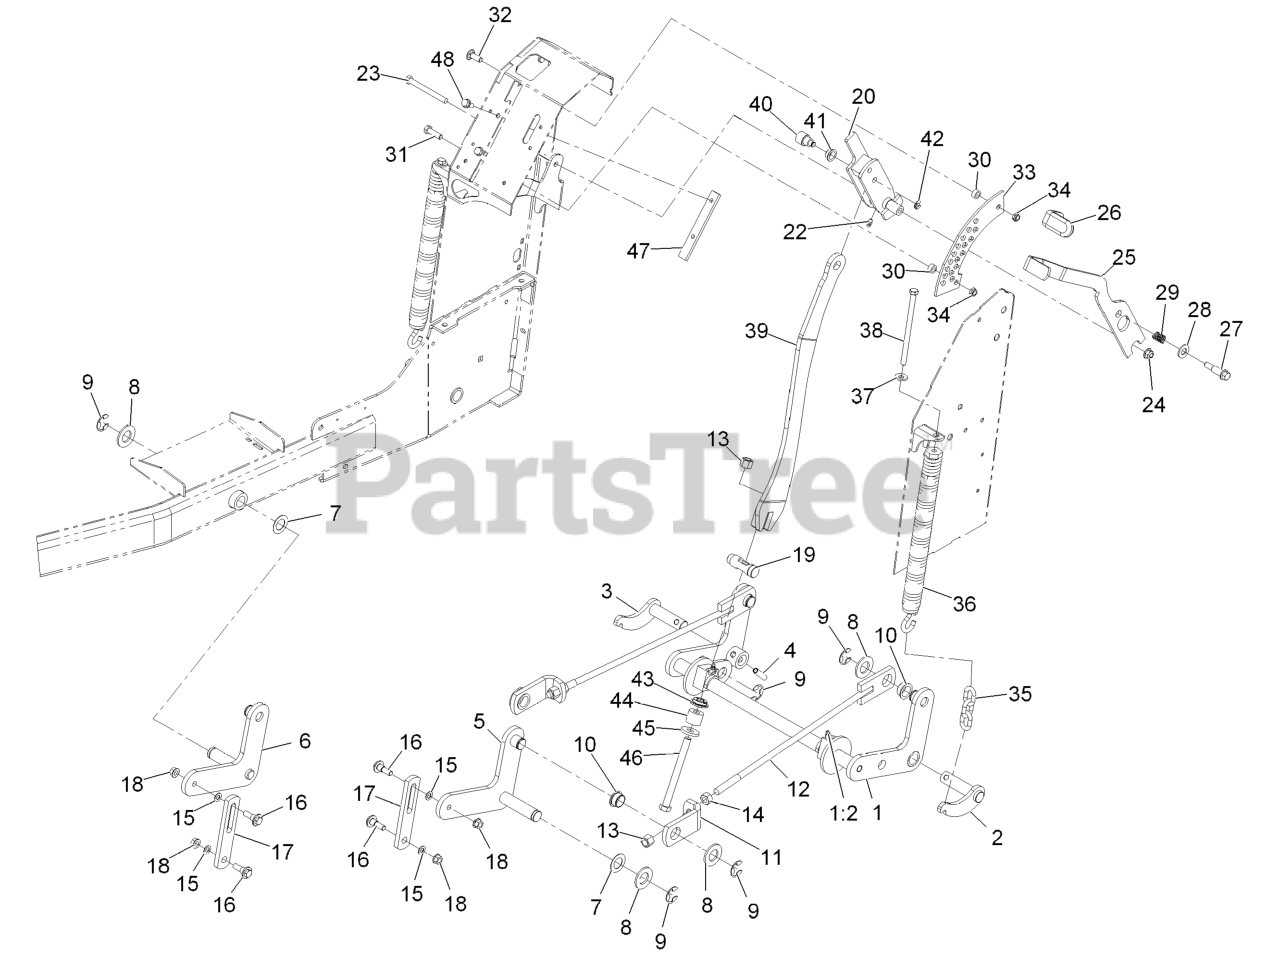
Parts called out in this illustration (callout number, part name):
1	REAR CROSSSHAFT ASM
1:2	FITTING-LUBE, 45 DEG
2	SHAFT-PIVOT, LH
3	SHAFT-PIVOT, RH
4	PIN-SPIRAL
7	WASHER-THRUST
8	WASHER-FLAT
9	RING-RETAINING, EXT
10	BEARING-FLANGE
11	BRACKET-LIFT ROD
12	LIFT ROD ASM
13	NUT-LOCK, NI
14	NUT-HH
16	SCREW-SHOULDER, HHF
17	LINK-LIFT
19	PIN-HOC
20	HOC HANDLE ASM
22	FITTING-GREASE
23	SCREW-HH
24	NUT-HF, NI
25	LEVER-HOC
26	GRIP-LEVER
27	SCREW-SHOULDER
28	WASHER-FLAT
30	SPACER
31	SCREW-HH
32	SCREW-CARR
33	BRACKET-HOC
35	CHAIN-DECKLIFT
36	SPRING-EXTENSION
37	WASHER-BELLEVILLE
38	BOLT-TAP, HH
39	BAR-LIFT
40	HUB-PIVOT
41	BEARING-FLANGE
42	RING-RETAINING
43	SEAT-SPRING
44	SPRING-URETHANE
46	SCREW-HH
47	SKID-HANDLE, LIFT
48	SCREW-THD ROLL, HWH
